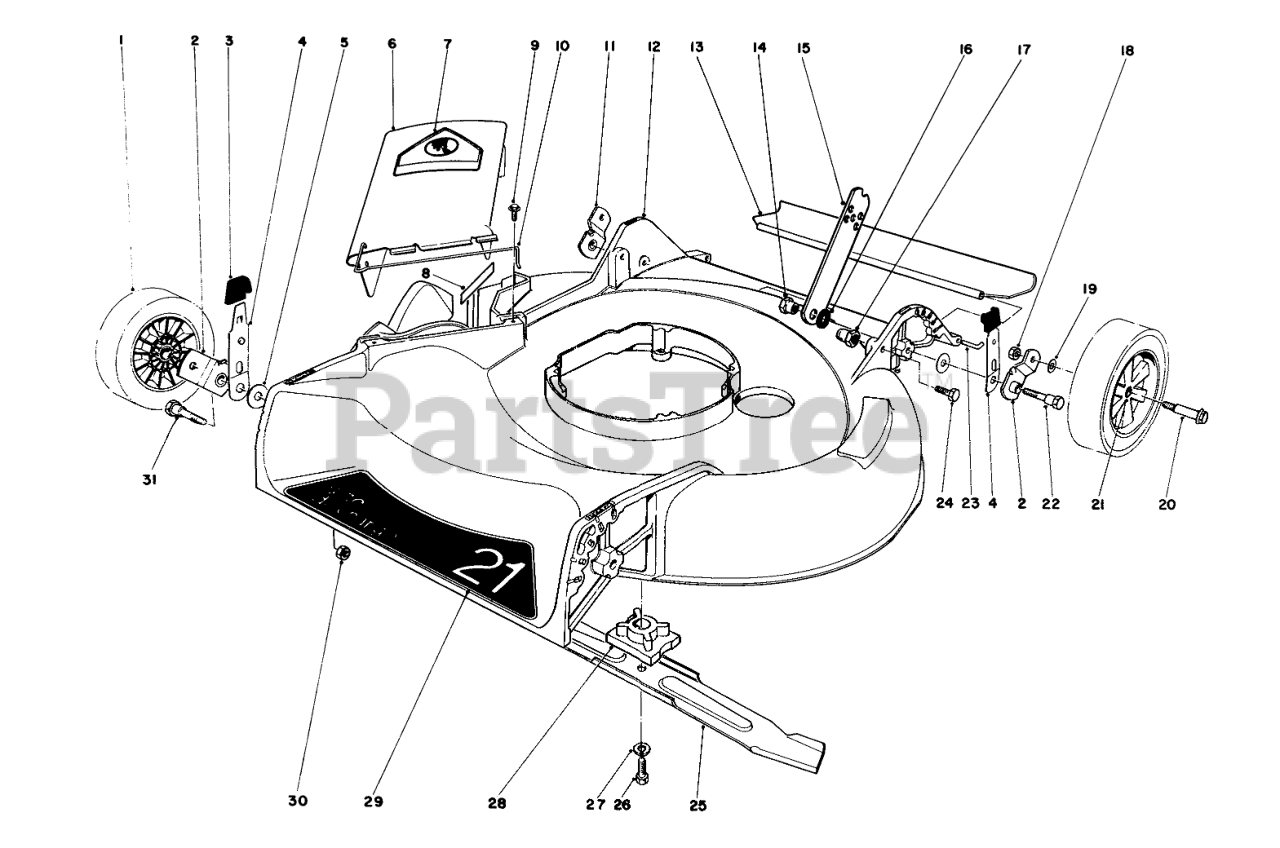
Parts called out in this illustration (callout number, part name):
1	Wheel & Tire Assembly (Incl. Ref. #21)
2	Pivot Arm
3	KNOB-ARM
4	SPRING ARM ASM
5	WASHER-PIVOT
6	Deflector Assembly (Incl. Ref. #7 & 10)
7	DECAL-DANGER
8	Decal
9	SCREW-HWH
10	SPRING HINGE
11	Pivot Arm
12	HOUSING/DECAL
13	REAR SAFETY SHIELD 21
14	HANDLE PIVOT NUT
15	HANDLE LATCH
16	SPACER
17	HANDLE PIVOT NUT
18	NUT-LOCK
19	WASHER
20	WHEEL BOLT
21	BUSHING
22	PIVOT SCREW
23	SHIELD ROD
24	SCREW-HH
25	Blade
26	SCREW-HH
27	WASHER-LOCK
28	BLADE RETAINER
29	Decal-Side Discharge
30	NUT-LOCK, NI
31	PIVOT SCREW
